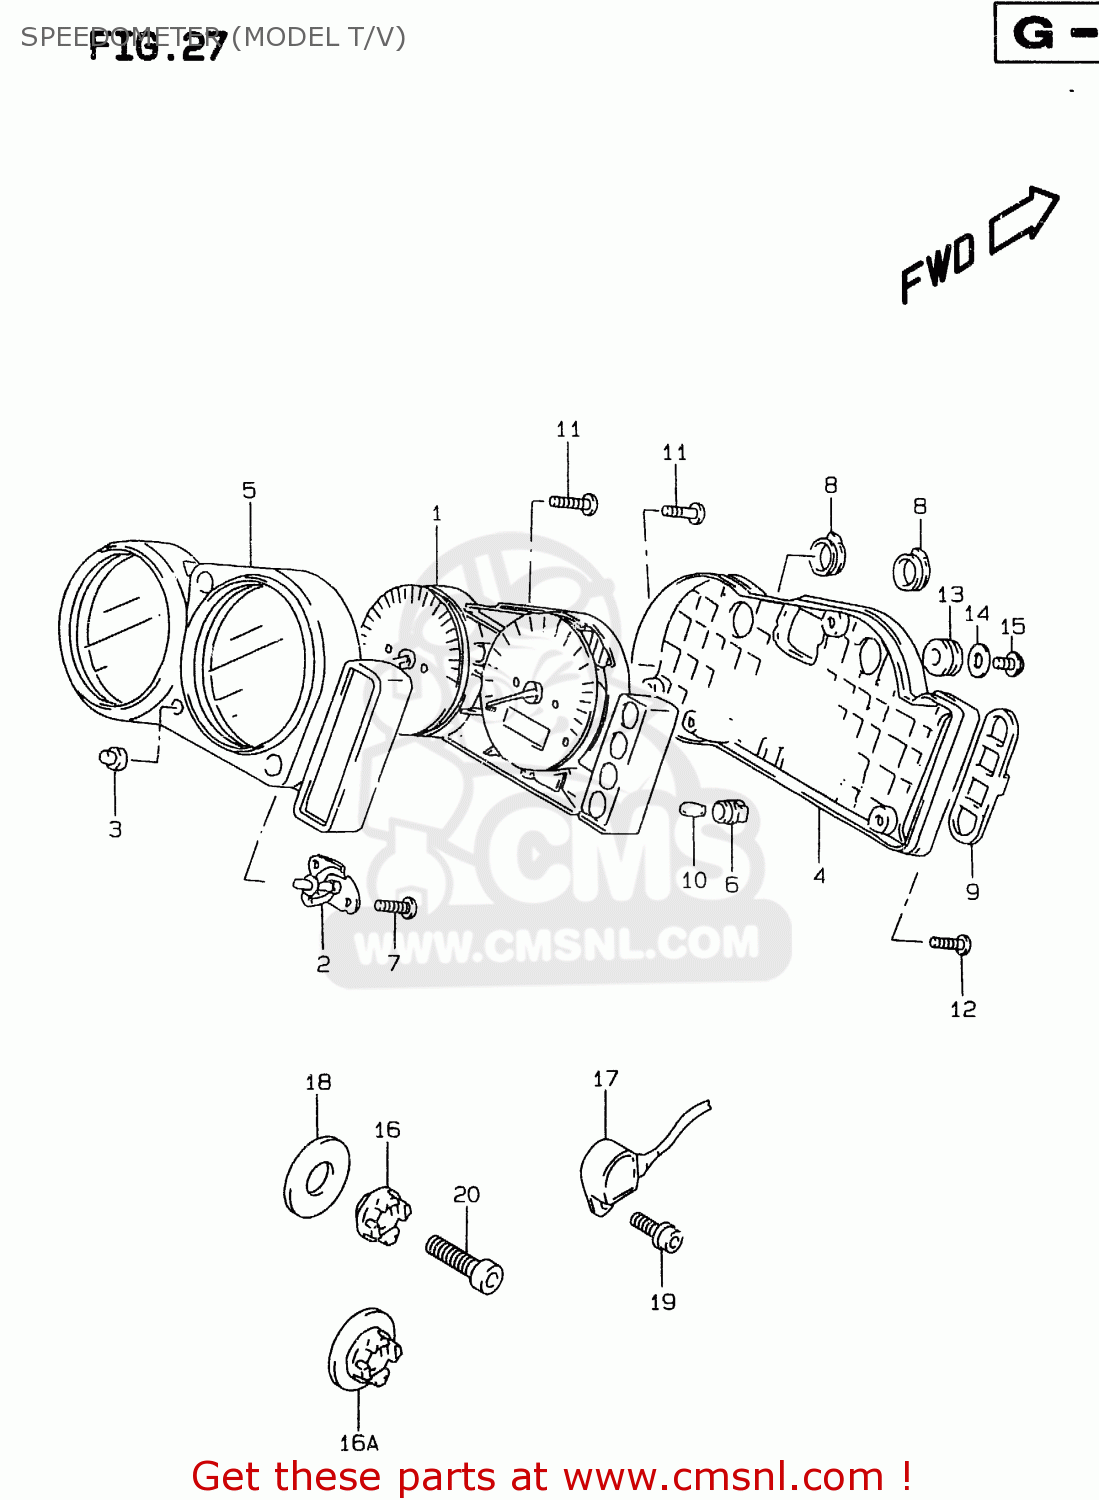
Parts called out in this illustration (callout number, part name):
1	SPEEDOMETER (MILE/KILO)
2	ATTACHMENT,SWITCH
3	SWITCH,GUM
4	CASE ASSEMBLY
5	VISOR
6	SOCKET
7	SCREW(3X10)
8	CAP,BLIND NO.1
9	CAP,BLIND NO.2
10	BULB(12V1.7W,T6.5)
11	SCREW
12	SCREW
13	CUSHION,METER
14	WASHER(5.5X16X1.2)
15	SCREW
16	ROTOR,SPEED
16A	ROTOR,SPEED
17	SENSOR,SPEED
18	WASHER(14.2X34X1)
19	BOLT
20	BOLT
